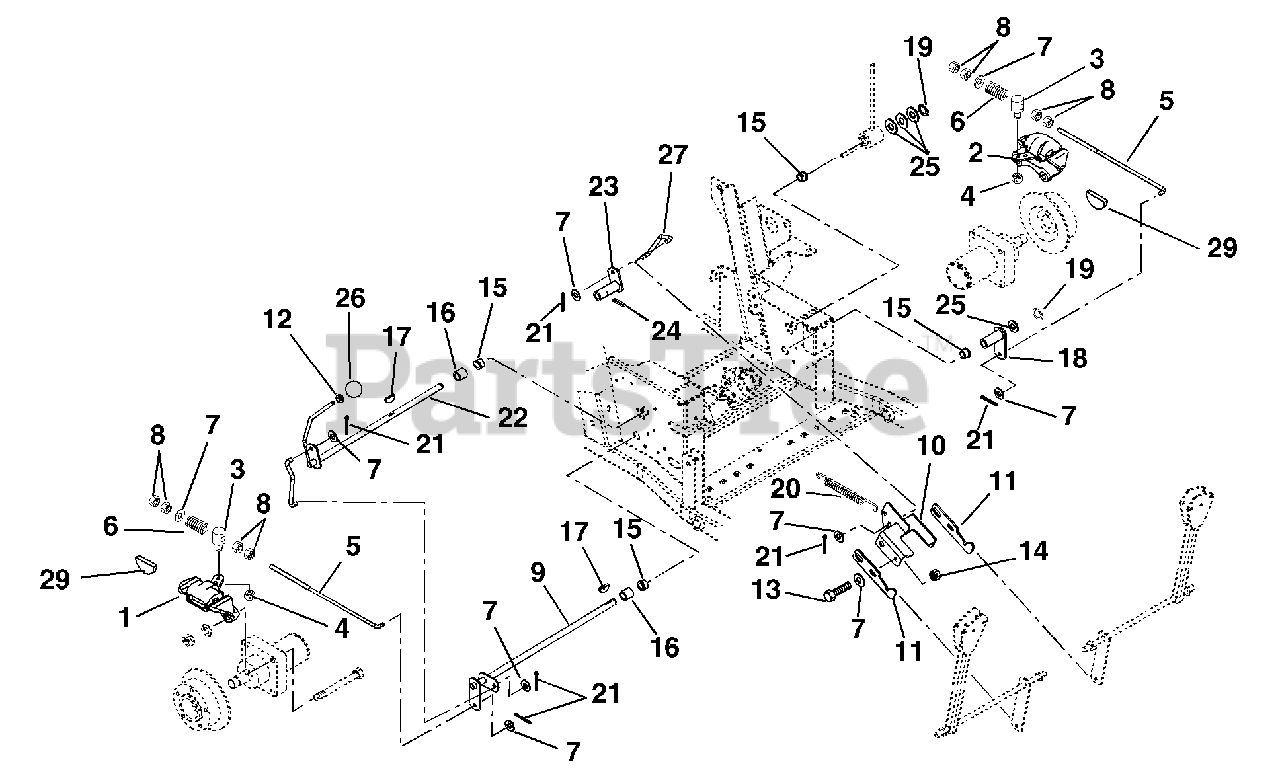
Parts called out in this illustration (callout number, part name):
1	Caliper, Park Brake (CW) Right Hand
2	Caliper, Park Brake (CCW) Left Hand
3	Pivot-Brake Rod
4	Nut-Locking-Center .31-18
5	Rod-Brake 12 inch
6	Spring-Compression .143 x .710 x 2.00
7	Washer-Flat-Steel .406 x .812 x .065
8	Nut-Hex .38-16
9	Shaft-Brake Cross
10	Interlock-Fixed
11	Interlock-Adjustable
12	Nut-Hex-Jam .375 -16
13	Bolt-Hex .38-16 x 1.00 Grade 5
14	Nut-Locking-Center .38-16
15	Bushing-Flange .630 x 1.00 x .625
16	Spacer .630 x .878 x 1.000
17	Key-Woodruff .19 x .75 Hard #9
18	Arm-Brake Left-Hand
19	Ring-Retaining-External .625 x .050
20	Spring-Tension .105 x .85 x 5.00
21	Pin-Cotter External .09 x .75
22	Shaft-Brake Actuating
23	Actuator
24	Pin-Roll .125 x 1.00
25	Washer-Flat-Steel .627 x .990 x .032
26	Knob-Steering Lock
27	Rod-Brake Actuating
28	Pin-Cotter-External .09 x .75 r
29	Pad, Disk Brake
